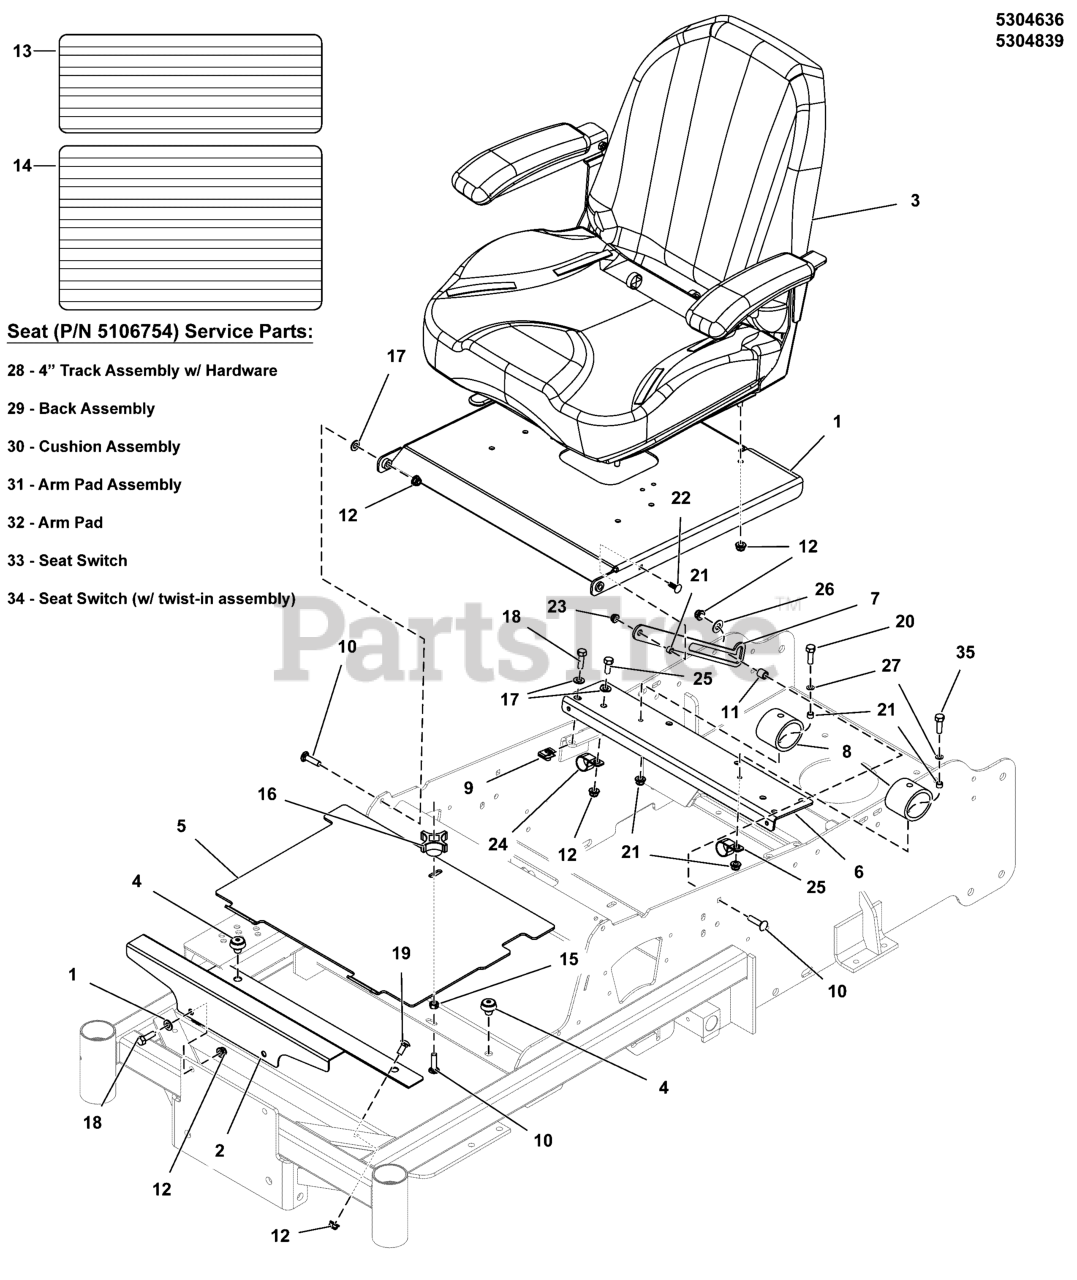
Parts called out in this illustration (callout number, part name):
1	WELD, PLATE, SEAT MOUNT - RED
2	PLATE, FLOOR RIGID, 50XT - RED
3	SEAT, 907, W/ARM REST, W/SWITCH, NO BEAD
4	MNT, VBRTN, RBBR
5	PLATE, REMOVABLE FLOOR, 50XT - RED
6	MOUNT, SEAT STOP - RED
7	PLATE, SEAT STOP LATCH - BLK
8	BUMPER, GBR-6, 200 IN-LBS
9	BODY CLIP, 5/16-18-7GA MATERIAL
10	BOLT, 5/16-18 X 1-1/4, CARRIAGE, GD5, CZ
11	SPACER, .33 X .50 X .50, YZ
12	NUT, 5/16-18 HEX NYLOCK FLANGE NUT
13	SAFETY WALK, FLOOR REST, 16.00 X 6.00
14	SAFETY WALK, FLOOR PLATE, S50X, 10X17.13
15	NUT, 5/16-1/8, HEX, CNTR LK, ZINC PHOS/OIL
16	KNOB-INT THR .312-18 4-ARM 2.12WD 1.06LG
17	WASHER, 5/16" SAE
18	BOLT, 5/16-18 X 1" GRD5 YZ
19	BOLT, 5/16-18 X 3/4, CARRIAGE, GD5, CZ
20	BOLT, 1/4-20 X 1" GD5 CZ
21	SPACER, .25 X .37 X .25
22	BOLT,1/4-20X0.750,GR5,STD NECK,SQ,ZC/CL
23	NUT, 1/4-20 Hex Nylock Flange
24	CLAMP, TUBE & WIRING, 1.062 ID
25	CLAMP, VINYL INSULATED, .625
26	WASHER, 5/16" USS
27	WASHER, 1/4 SAE
28	4" SL TRACK SET - 9" FLAT - W/HDWR
29	SEAT BACK ASSEMBLY, 186693VN1328
30	SEAT CUSHION ASSEMBLY, 186694VN1328
31	KIT, ARMREST (185872VN1328)
32	ARM PAD, C13 SEAT
33	SWITCH, SEAT
34	SWITCH, NC, W/ TWIST-IN BASE
35	BOLT, 1/4-20 X 1-1/4 GD5 CZ
